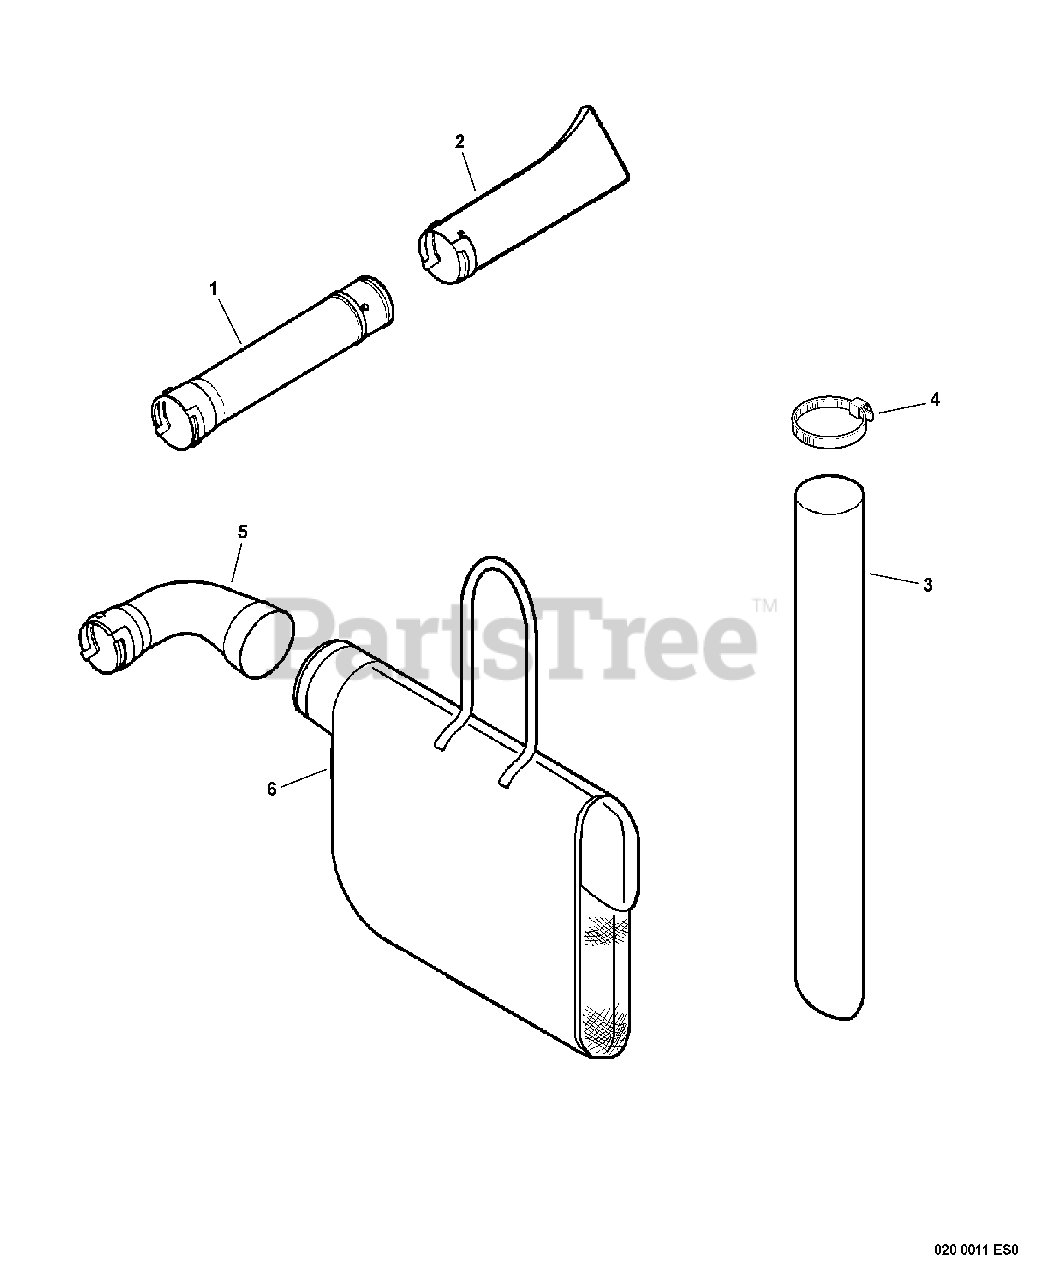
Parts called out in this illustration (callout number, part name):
1	TUBE, BLOWER - STRAIGHT
2	TUBE, BLOWER - NOZZLE
3	TUBE, VACUUM
5	TUBE, DEBRIS
6	BAG, DEBRIS
